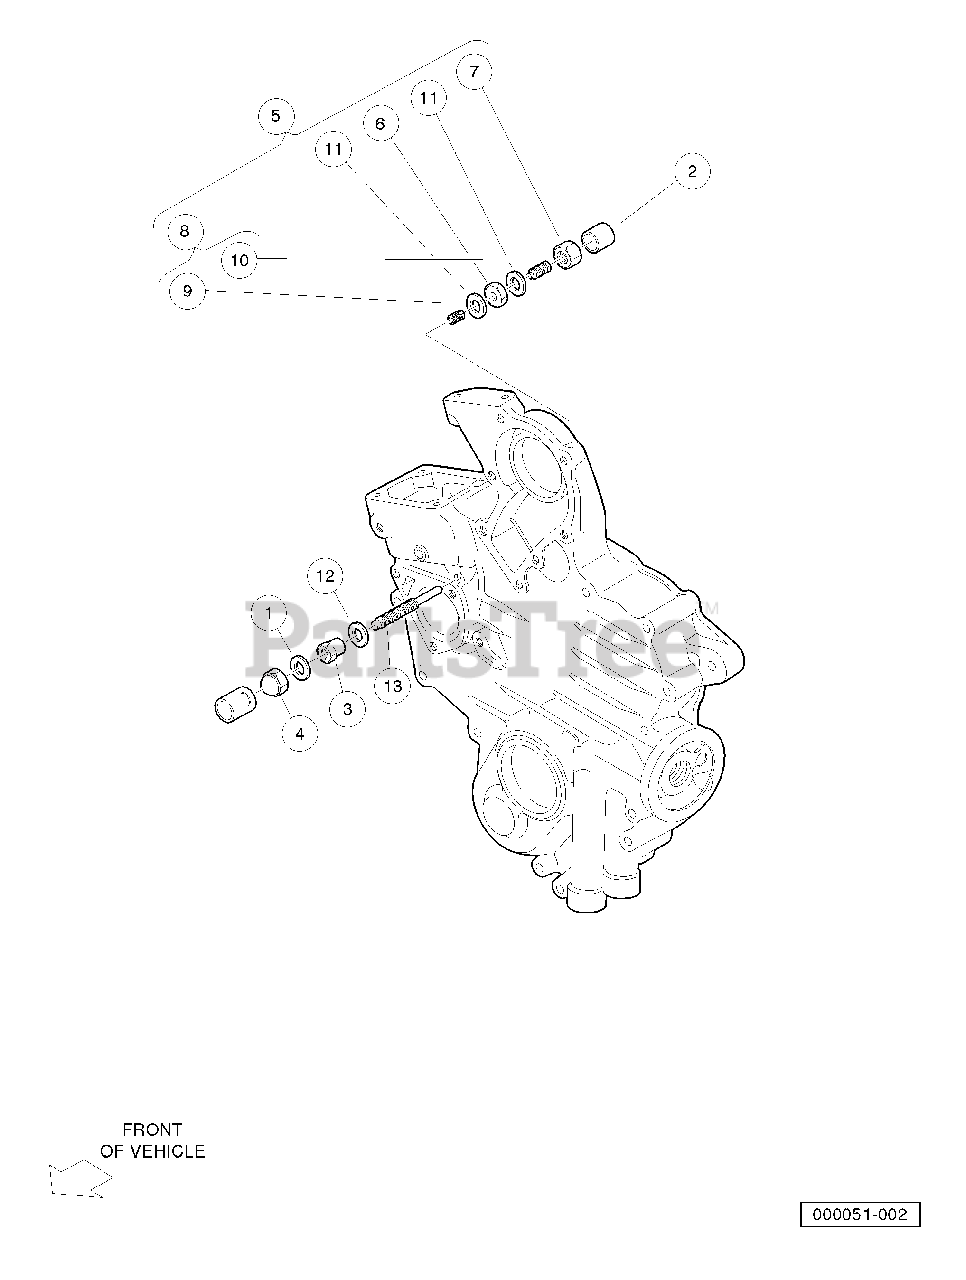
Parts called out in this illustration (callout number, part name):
1	Gasket, 6 X 10
2	Cap, Bolt Assy
3	Nut, Lock, Special
4	Nut, Special
5	Assy, Idle Apparatus
6	Nut, M8, D722 Idle App, Specl
7	Nut, M8, D722 Idle App
8	Assy, Bolt, Adjusting
9	Spring, Idle Apparatus
10	Stud, Idle Adjustment
11	Gasket, Idle Apparatus, Rear
12	Gasket, Idle Apparatus, Front
13	Bolt, Idle Adjusting
